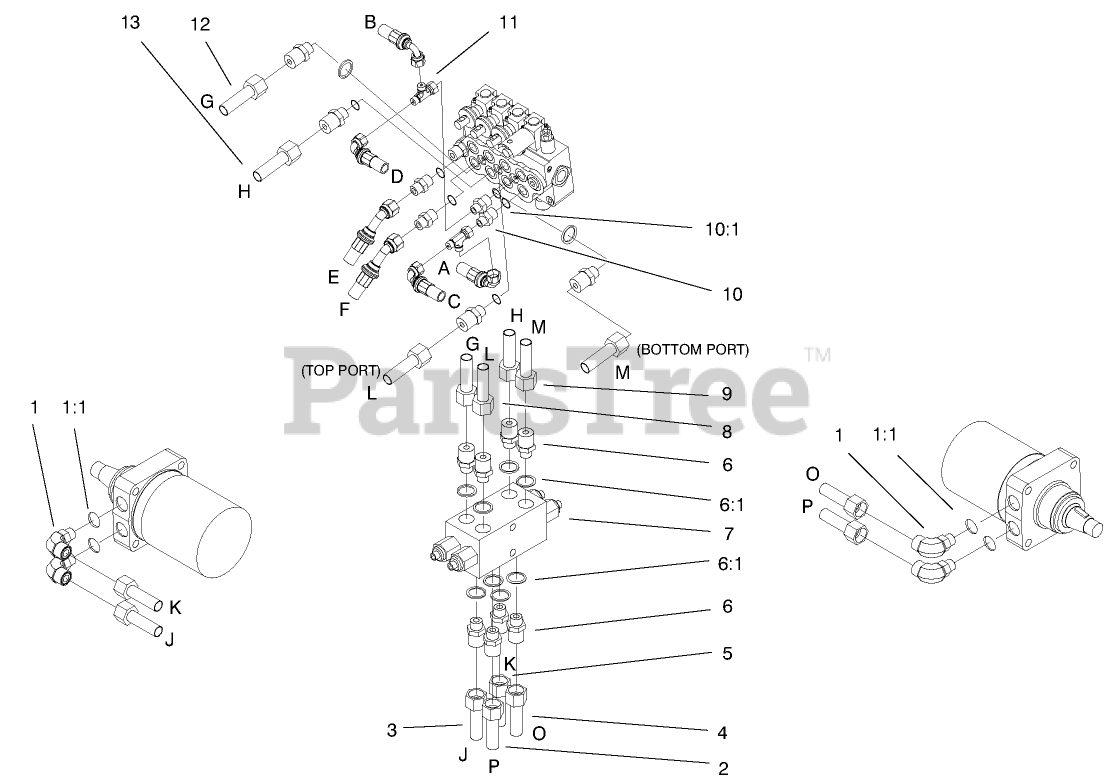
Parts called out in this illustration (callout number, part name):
1	FITTING-ELBOW, 90 DEG
1:1	O-RING
2	TUBE-HYD
3	TUBE-HYD
4	TUBE-HYD
5	TUBE-HYD
6	FITTING-STRAIGHT
6:1	O-RING
7	VALVE-COUNTERBALANCE
8	TUBE-HYD
9	TUBE-HYD
10	FITTING
10:1	O-RING
11	CONNECTOR-SWIVEL
12	TUBE-HYD
13	TUBE-HYD
